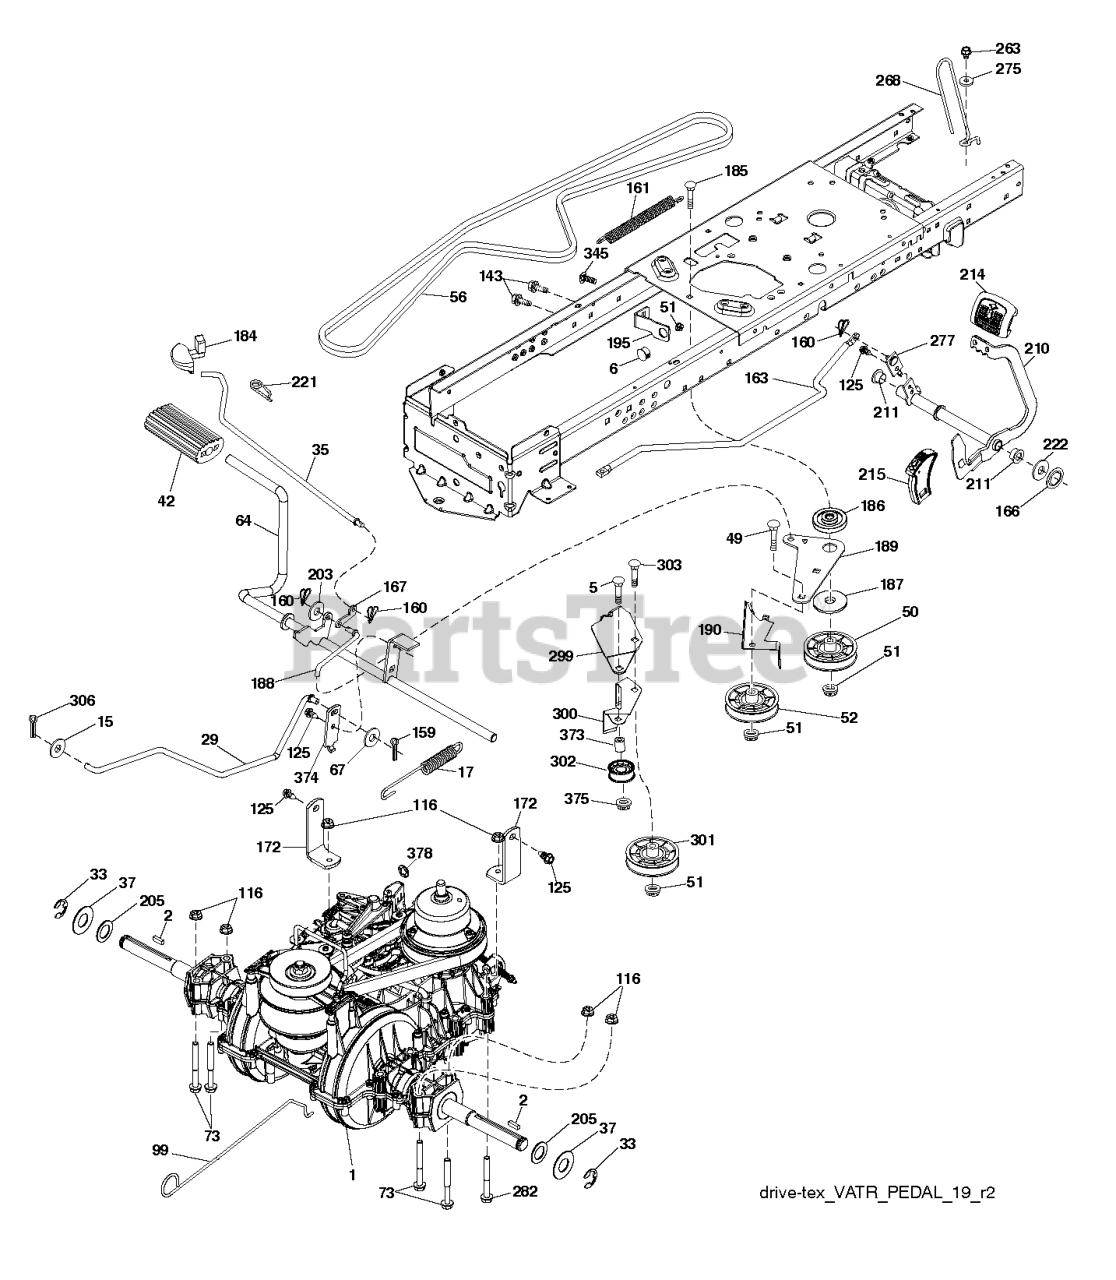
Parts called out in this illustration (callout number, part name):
2	SQUARE KEY
6	BUSHING.SNAP.NYL.BLK.
15	WASHER
17	SPRING BRAKE VARIATOR
29	BRAKE.VARIATOR.SD3
35	ROD.CNTRL.PARK.PREDATOR.LT.TEX
37	WASHER.HARDENED
42	PEDAL COVER T
49	BOLT
50	IDLER.FLAT.910.OFFSET
51	NUT LOCK FLG 3/8-16 UNC
52	IDLER.V-GROOVE.910.OFFSET
56	BELT.V.EURO.VARIATOR
64	SUBASM.SHAFT.PEDAL.BRAKE
67	WASHER
73	BOLT HEX 5/16-18 GR 5
99	ROD.BYPASS.VARIATOR.GEN2
116	NUT LOCK HEX FLANGE 5/16-18
125	SCREW
143	SCREW LT
159	COTTER PIN
160	RETAINER CLIP
161	SPRING, RETURN LT
163	ROD.CONTROL.PEDAL.VARIATOR
166	NUT.PUSH.625
167	LATCH.BRAKE.SPRING
172	STRAP.TORQUE.VARIATOR
184	HANDLE.PARKNG BRK.PRED.LT.428
186	SPACER.RETAINER
187	WASHER 12/32X2X10GA
188	RP.LINK.CLUTCH.GROUND.DRIVE
189	BELLCRANK.GROUND.DRIVE.TEX.
190	KEEPER.BELLCRANK.DRIVE
195	BRACKET.BRAKE.BRAKE.VAR.SD
203	WASHER
210	WELDMENT.PEDAL.VARIATOR
211	BEARING.NYLON
214	PEDAL.FORWARD.PAD.TEX
215	CAP.PEDAL.REVERSE.VARIATOR
221	RETAINER.SPRING.CLIP.H
222	WASHER 21/32 X 1-1/4 X 10 GA.
263	SCREW, 3/8-16X3/4
268	GUARD MUFFLER
275	WASHER
277	SUBASM.LINK.ROCKER.PEDAL
282	BOLT HEX FLGHD 5/16-18X3 GR. 5
299	BRACKET.MOUNT.IDLERS
300	KEEPER.IDLERS.REAR.VARIATOR
301	PULLEY.IDLER.V-GROOVE
302	PULLEY.IDLER.FLAT.2"
303	BOLT CARRIAGE
306	PIN COTTER
345	BOLT
373	SPACER.IDLER
374	ARM.CONTROL.BRAKE
375	LOCKNUT
378	NUT.PUSH.8MM
